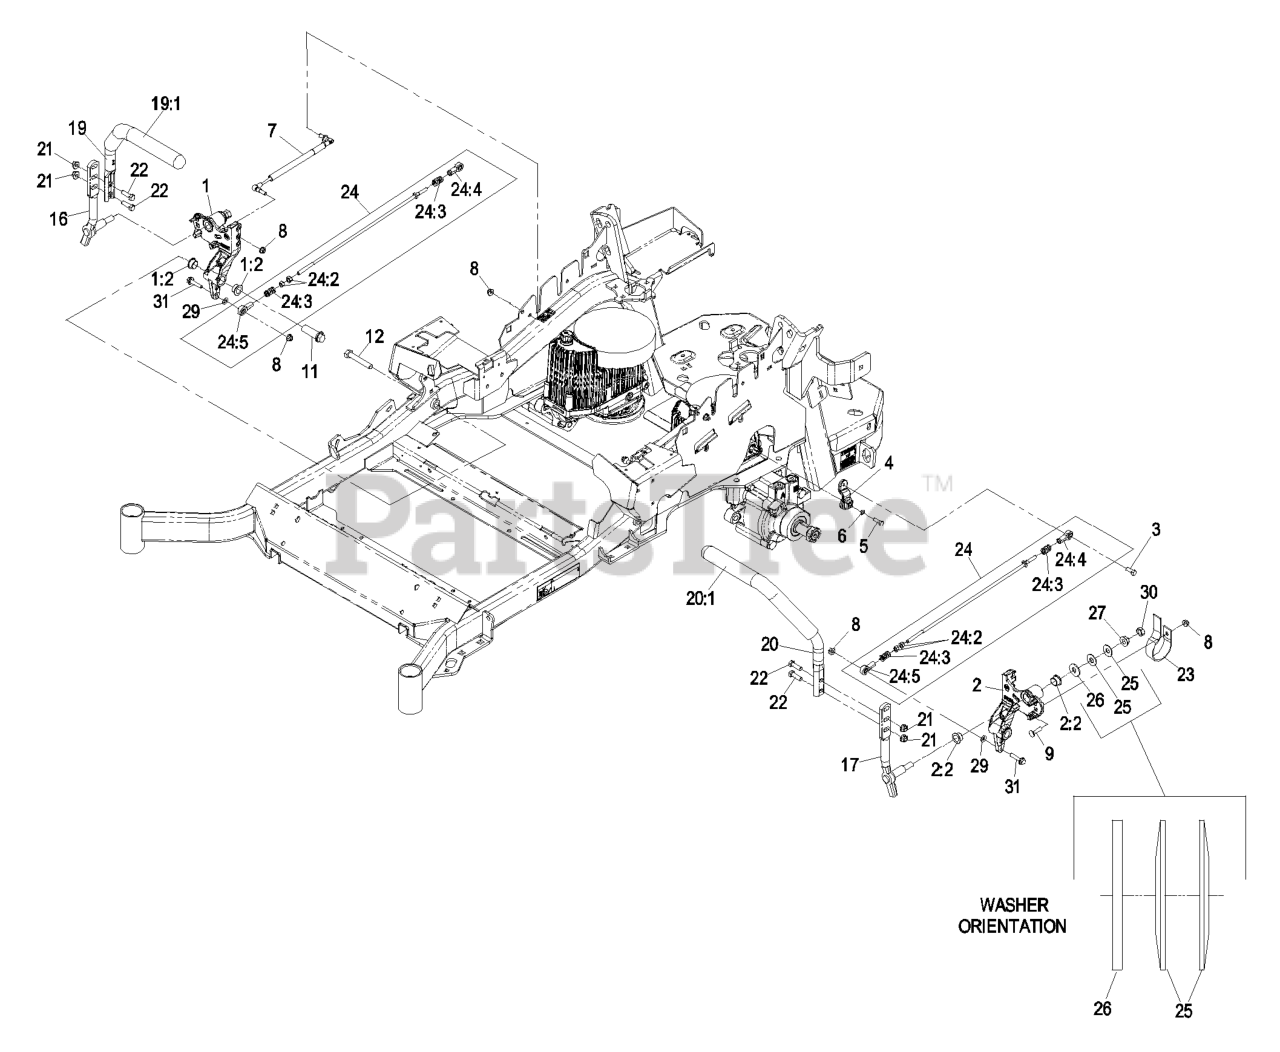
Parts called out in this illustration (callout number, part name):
1	RH MOTION CONTROL AND BUSHING ASM
1:2	BUSHING-FLANGE
2	LH MOTION CONTROL AND BUSHING ASM
2:2	BUSHING-FLANGE
3	SCREW-HH, THREAD LOCKING
4	ARM-CONTROL, PUMP
5	SCREW-HH
6	WASHER-SPRING
7	DAMPER-CONTROL, MOTION
8	NUT-HF, NI
9	BOLT-CARR
11	HUB-THREADED
12	SCREW-HH
16	LEVER-CONTROL MOTION, RH
17	LEVER-CONTROL MOTION, LH
19	RH STEERING HANDLE ASM
19:1	GRIP-LEVER, CONTROL
20	LH STEERING HANDLE ASM
20:1	GRIP-LEVER, CONTROL
21	NUT-HF, NI
22	SCREW-HH
23	SPRING-LEAF
24	FRONT PUMP LINKAGE ASM
24:2	NUT-HEX
24:3	SPRING-COMPRESSION
24:4	BALLJOINT-LH
24:5	BALLJOINT-RH
25	WASHER-SPRING
26	WASHER-FLAT
29	WASHER-PLAIN
30	NUT-JAM
31	SCREW-HHF
